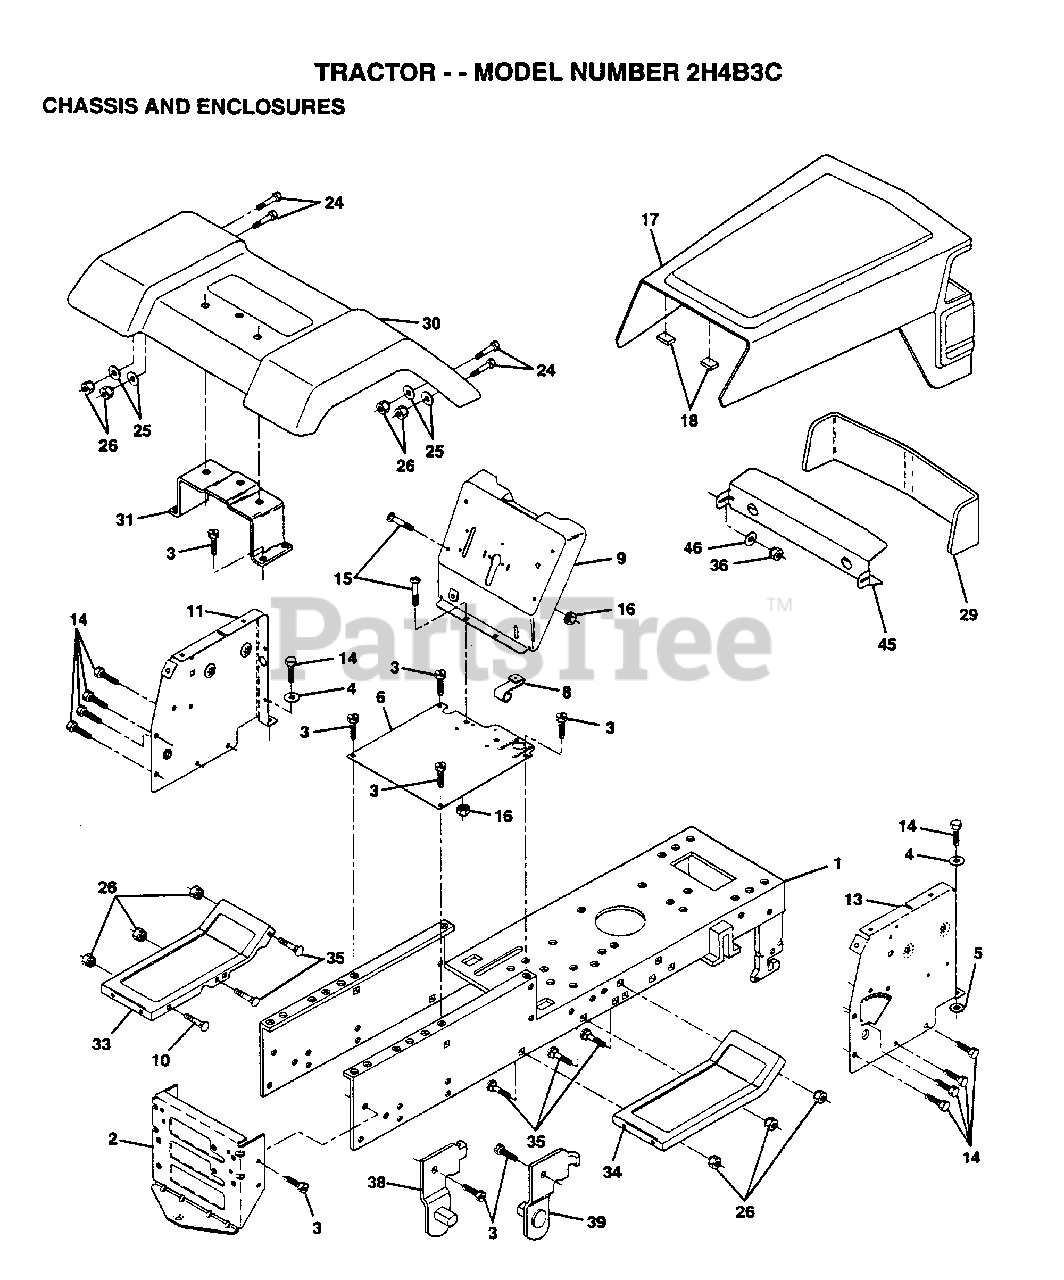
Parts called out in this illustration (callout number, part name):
3	SCREW
4	WASHER
5	LOCKWASHER
8	"CLIP,INSULATOR"
9	DASH SILKSCRN 1
11	DASH PANEL LH
14	SCREW LT
15	SCREW
17	HOOD/GRILL ASM
24	BOLT
25	WASHER
26	NUT
30	FENDER
31	BRKT FENDER
33	FOOTREST LH
34	FOOTREST RH
35	BOLT
36	PAL NUT LT
38	BRACKET ASM LH
39	BRACKET ASM RH
46	RETAINER
